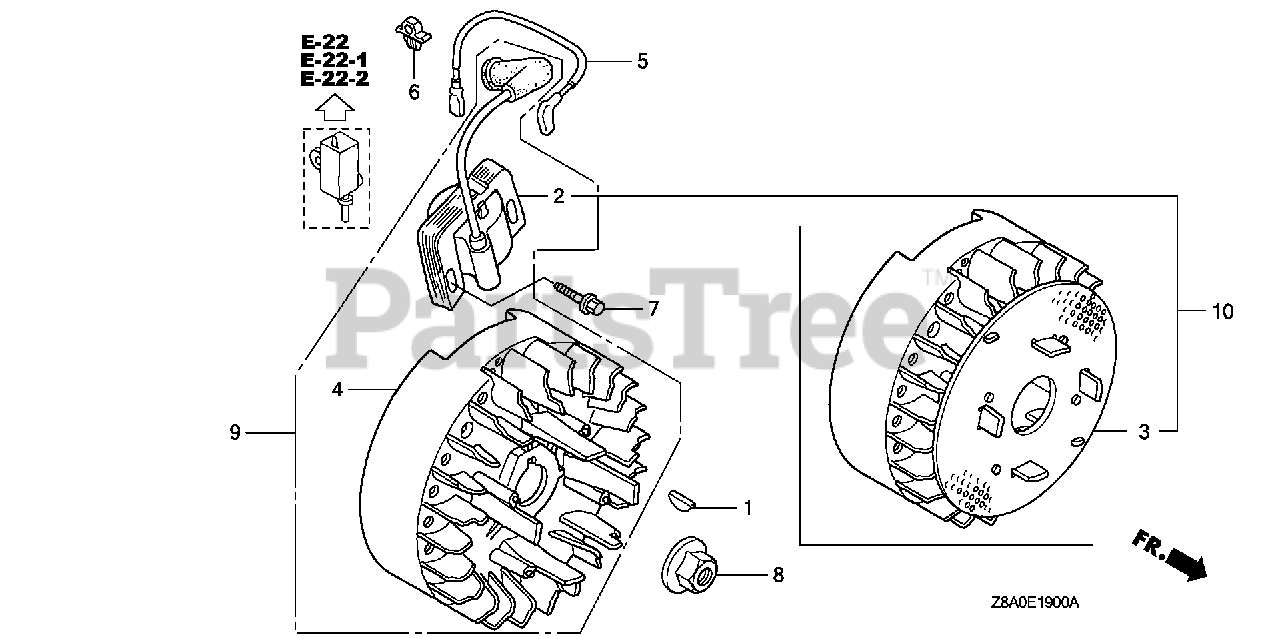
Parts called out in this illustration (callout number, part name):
1	KEY, SPECIAL WOODRUFF (25X18)
2	COIL ASSY., IGNITION (USE FOR F/W OF TEC) (TEC)
2	COIL ASSY., IGNITION (PHELON) (USE FOR F/W OF PHELON)
2	COIL ASSY., IGNITION (PHELON)
4	FLYWHEEL COMP. (TEC) (USE FOR IGN. COIL OF TEC)
4	FLYWHEEL COMP. (PHELON) (USE FOR IGN. COIL OF PHELON)
5	WIRE, STOP SWITCH
6	HOLDER, STOP SWITCH WIRE
6	HOLDER, WIRE (FASTEX)
7	BOLT, FLANGE (6X20) (CT200)
8	NUT, SPECIAL (14MM)
9	FLYWHEEL KIT
